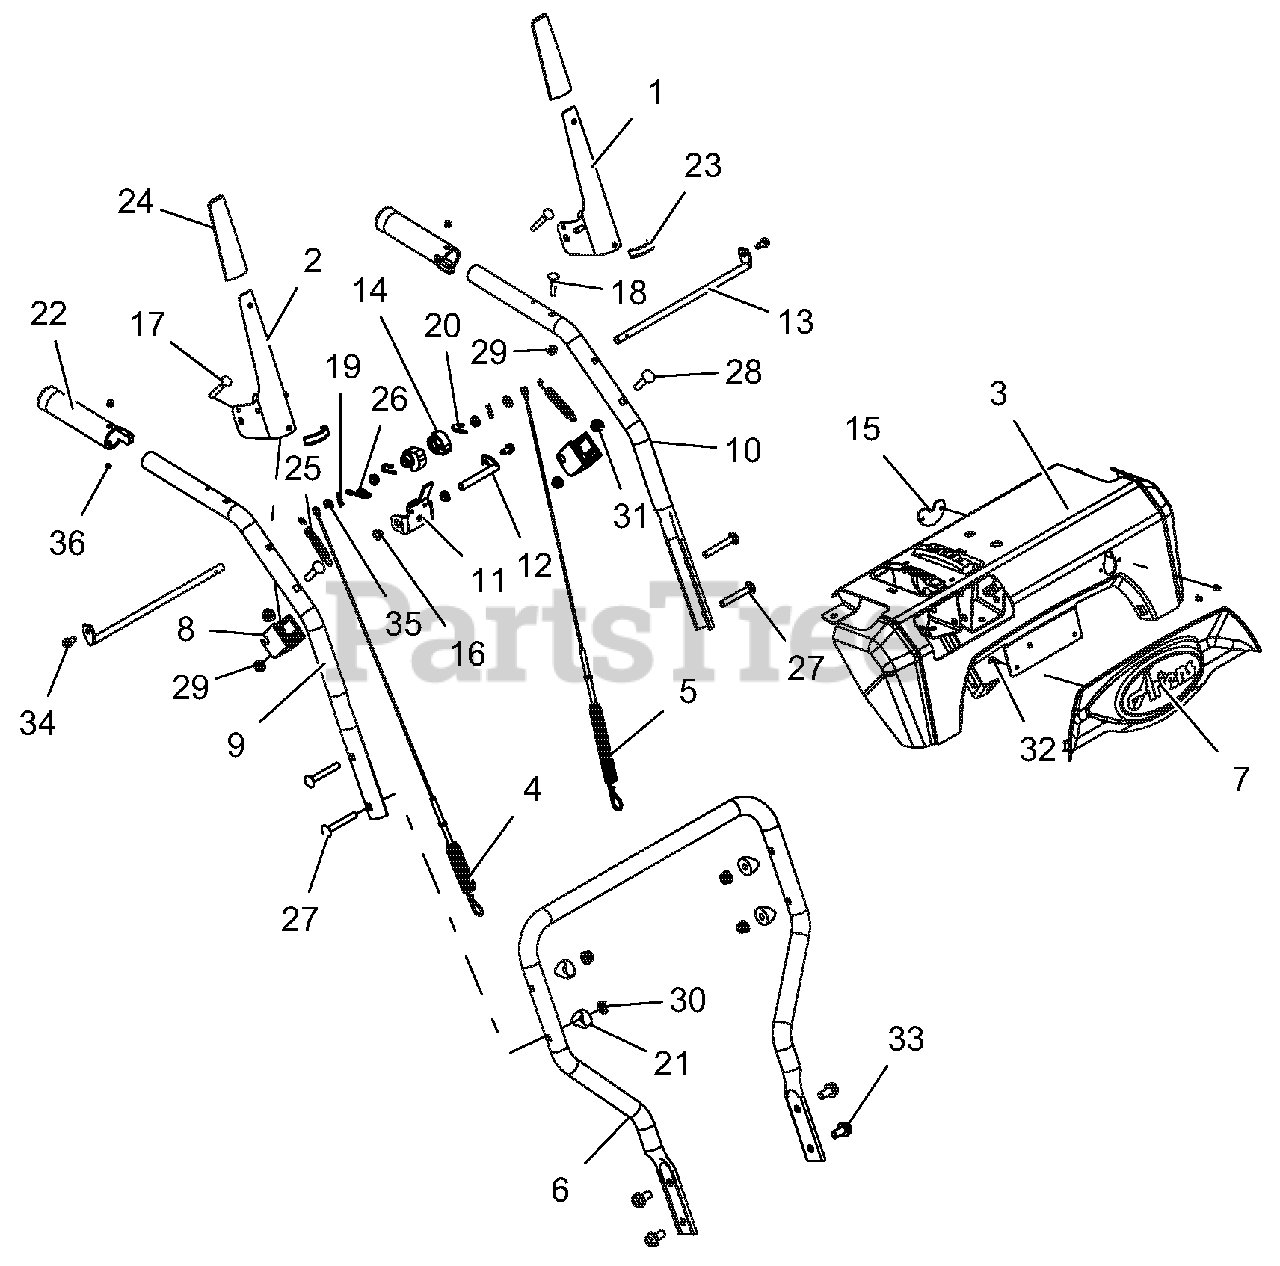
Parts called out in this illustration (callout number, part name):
1	LEVER, CLUTCH-LH
2	LEVER, CLUTCH-RH
3	WELDMENT,DASH PANEL,LRG,ID
4	CABLE, AUGER (DELUXE & PRO)
5	CABLE, UPPER TRACTION
6	HANDLEBAR, LOWER - DELUXE
7	DASH BEZEL, ARIENS LOGO - PRO
8	BLOCK, CLUTCH PADDLE
9	HANDLEBAR, UPPER - RH
10	HANDLEBAR, UPPER - LH
11	BRACKET, INTERLOCK ARM
12	ROD, PIVOT - INTERLOCK
13	ROD, PADDLE MOUNT - PRO
14	CAM, INTERLOCK
15	COVER, DASH BRKT, ID
16	BUSHING, POLYLINER-.38 SNAPIN
17	BLT-RDHDXLSQNK .25-20X2.0 G5YZ
18	BLT-RDHDXLSQNK.25-20X1.25 G5ZC
19	PIN-HAIR INT .06X.18X.77
20	PIN, SPRING CLIP
21	SPACER, HANDLEBAR
22	HEATED GRIP, MAGURA
23	EDGING, CLUTCH PADDLE - 2.00"
24	CLUTCH PADDLE SLEEVE - GRAY
25	SPRING, EXTENSION
26	SPRING-EXT .047X.438X1.45
27	@BLT-RDHDSQNK .31-18X2.25 G5YZ
28	@BLT-RDHDSQNK .31-18X1.50 G5YZ
29	@NUT-LK-CTR-FLG .25-20 YWZC
30	@NUT-LK-NYL-FLG .31-18 YWZC
31	@NUT-LK-TOP-FLG .31-18 YWZC
32	SCR-TAP #10X.50 BOSS INDHXHD
33	BLT-SERHFWH .38-16X.75 YWZC
34	SCR-TAP .25-20X.50 HWH TR YWZ
35	@WSHR-FL-STL.281X.62X.065 YWZC
36	RVT-POP #43 .125X.313 STL ZINC
